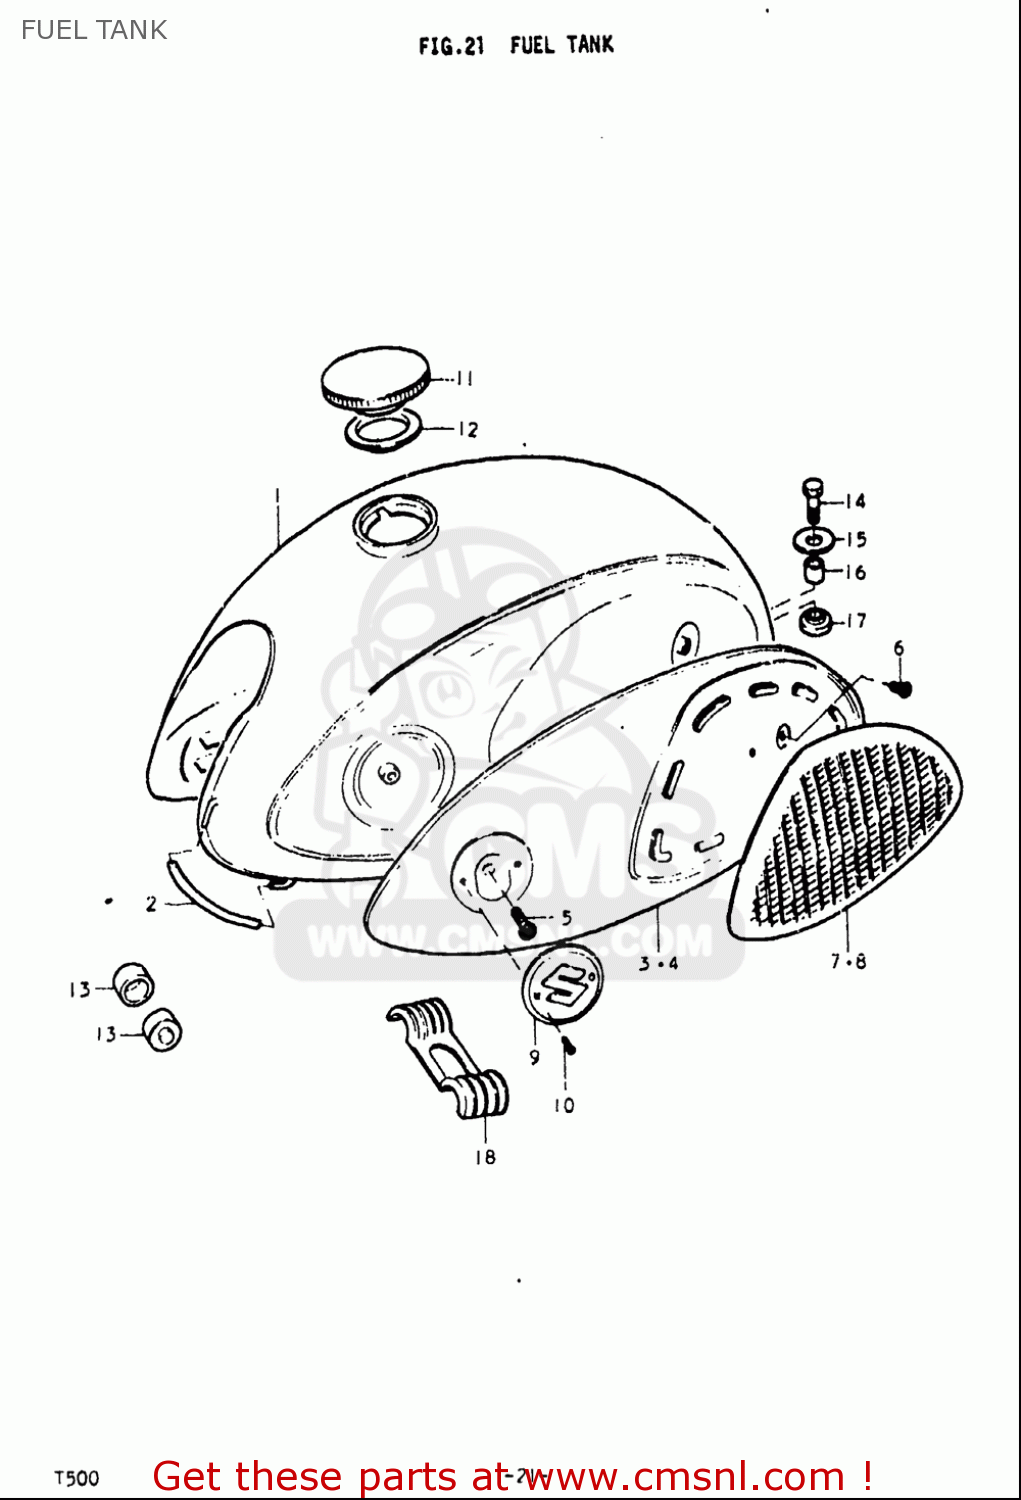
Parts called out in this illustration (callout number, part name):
5	SCREW
6	SCREW(5X6)
13	CUSHION
14	BOLT
16	SPACER(8.5X12X11)
17	BUSH(12X15X20)
